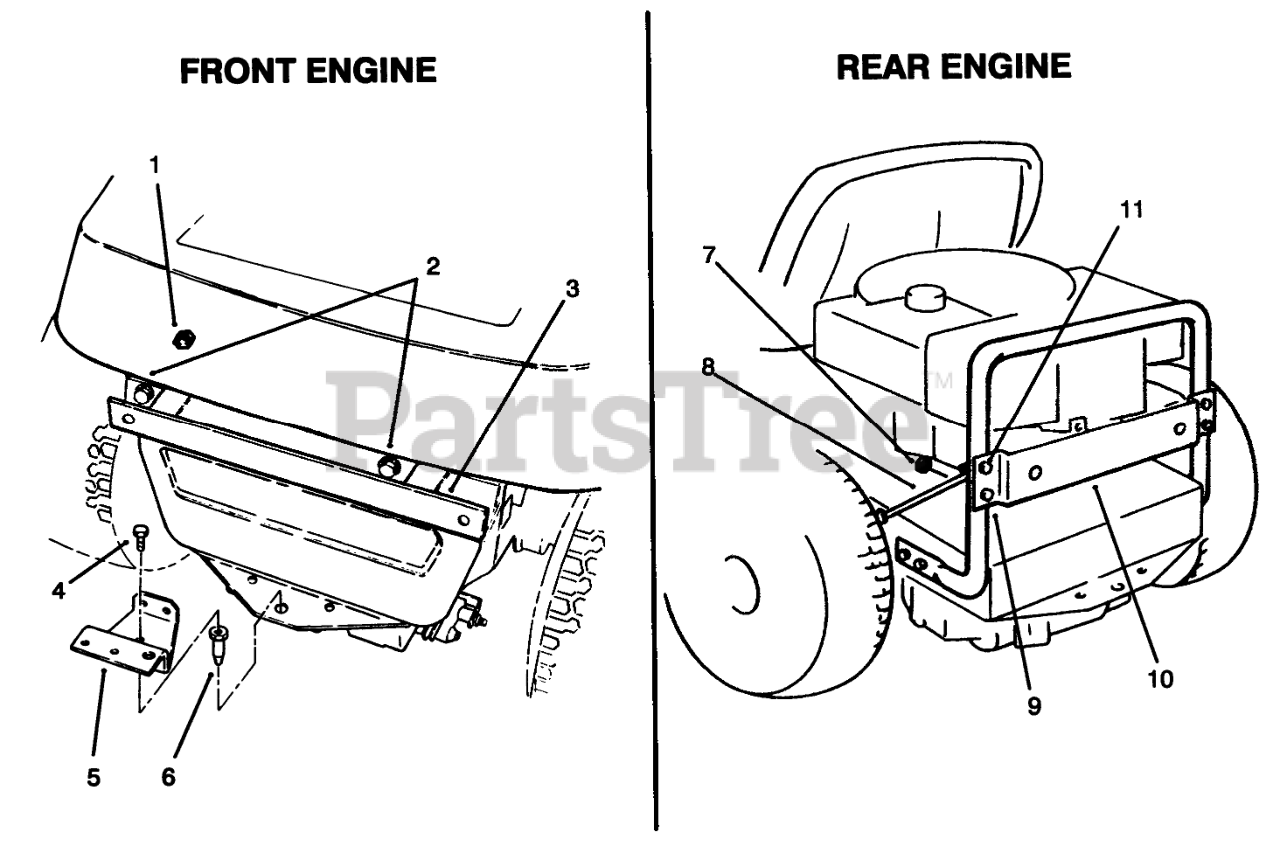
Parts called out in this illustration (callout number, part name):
1	NUT-LOCK, NI
2	SCREW-HH
3	Bracket-Channel
4	SCREW-HH
5	Bracket-Bagger Mounting
6	PIN-MOUNTING, LOWER
7	NUT-LOCK, NI
8	BAGGING KIT BRACE
9	SCREW-HH
10	Plate-Bagging Kit
11	SCREW-HH
